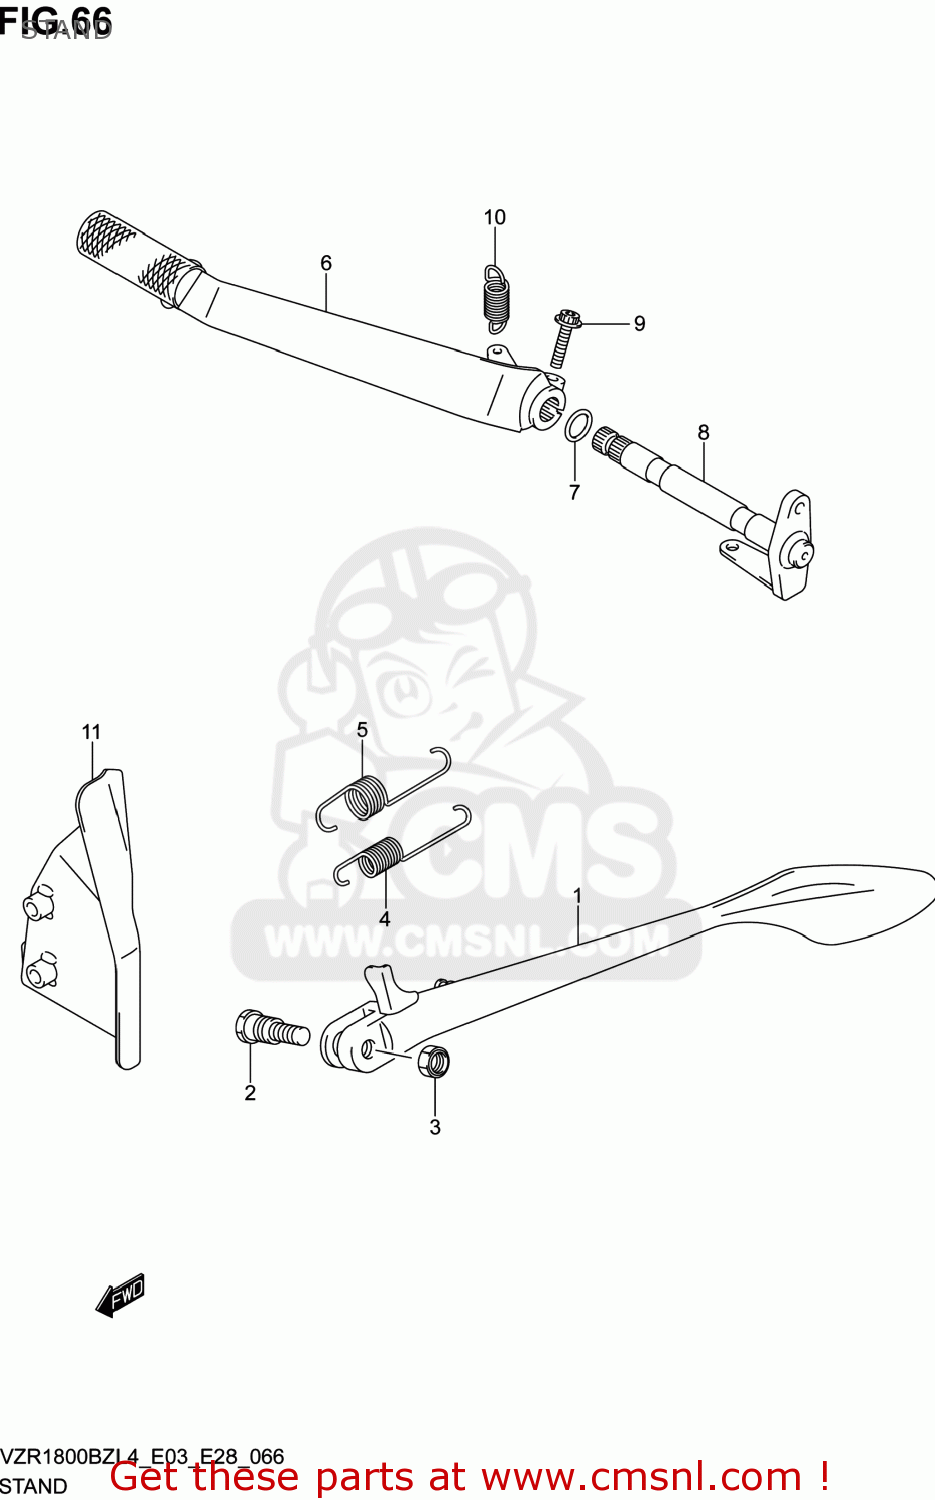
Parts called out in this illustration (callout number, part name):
1	STAND,PROP
2	BOLT(10X37.5)
3	NUT,PROP STAND
4	SPRING
5	SPRING
6	PEDAL,BRAKE
7	O RING(D:2.5,ID:13.8)
8	ARM,BRAKE ROD
9	BOLT
10	SPRING
11	GUARD,RR MASTER CYLINDER
